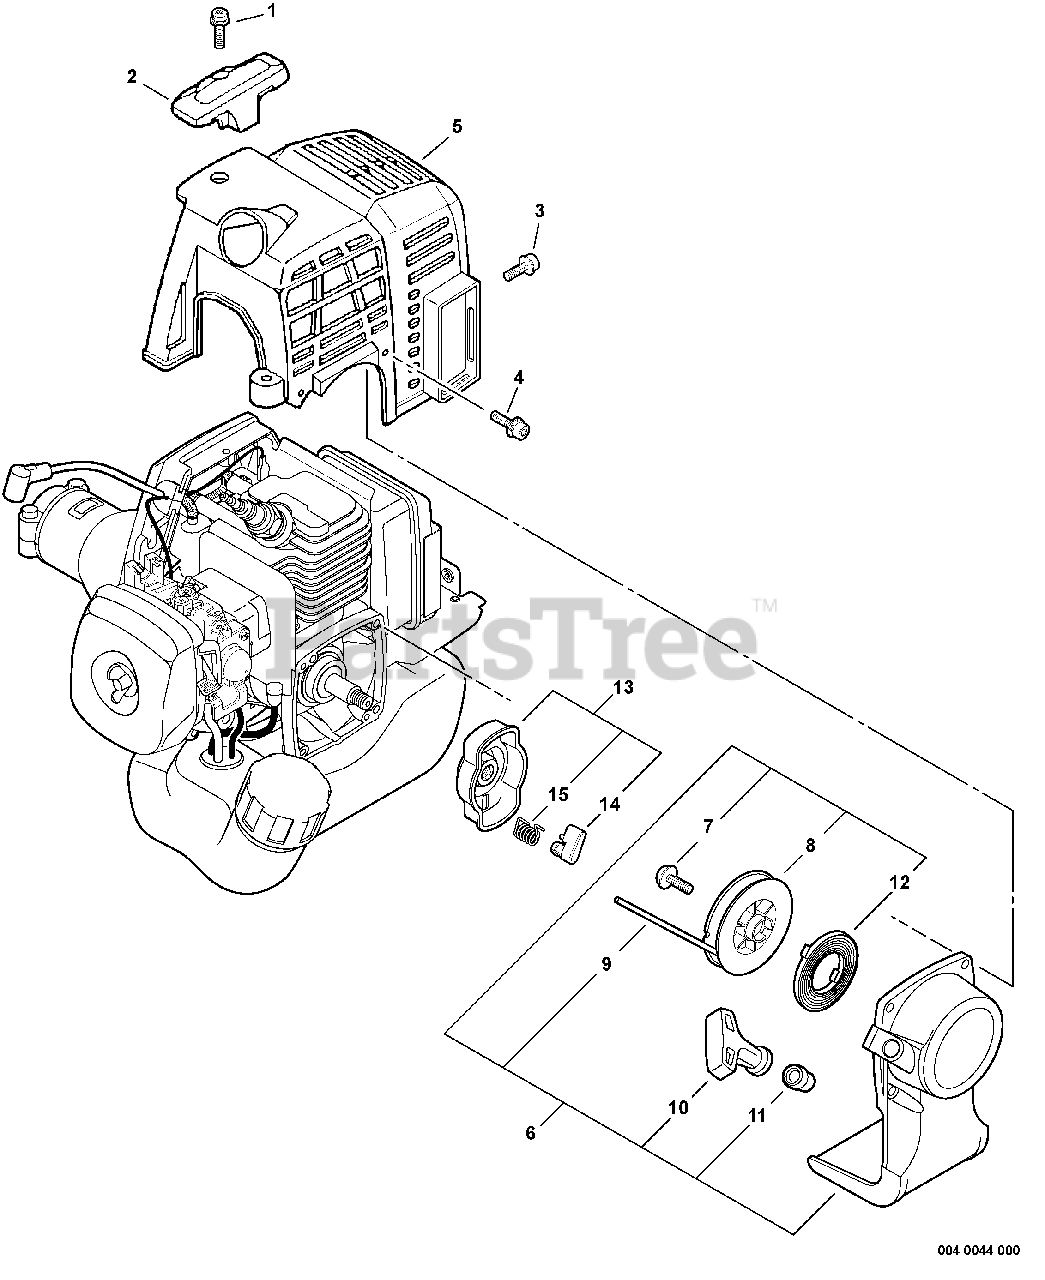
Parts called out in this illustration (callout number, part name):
1	SCREW - 5X16
2	GUARD - TOP
3	SCREW - 4X8
4	SCREW - 4X16
5	COVER, ENGINE
6	STARTER ASSY
8	REEL, ROPE
9	ROPE, STARTER - 3X1000
10	GRIP, STARTER
11	GUIDE, ROPE
12	SPRING, REWIND
13	STARTER PAWL ASSY
14	PAWL, STARTER - BLACK
15	SPRING, RETURN
